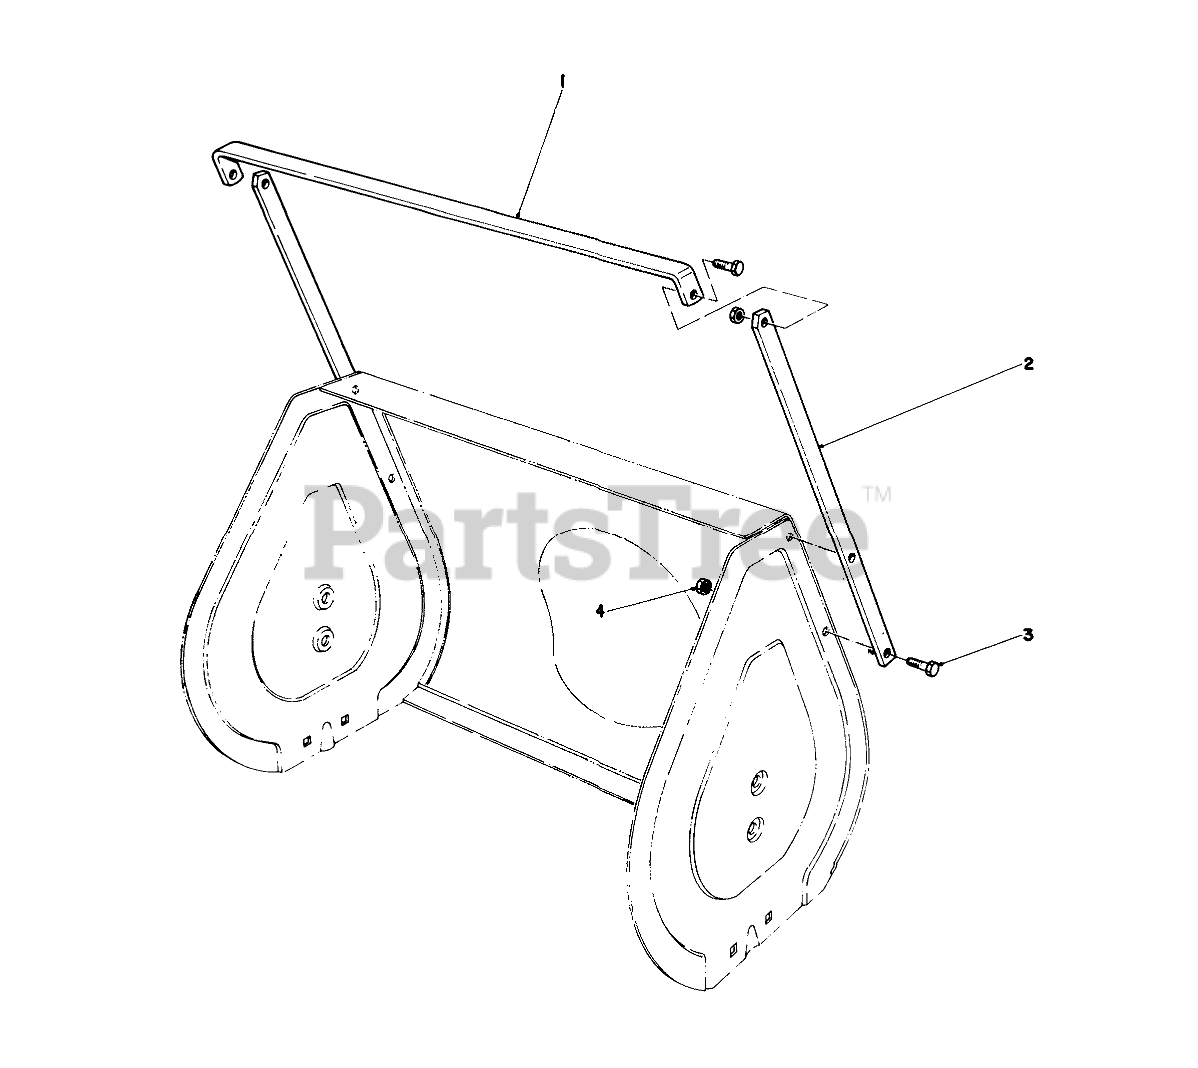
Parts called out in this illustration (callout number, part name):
1	Drift Breaker-Top
2	Drift Breaker-Side
3	SCREW-HH
4	NUT-LOCK, NI
